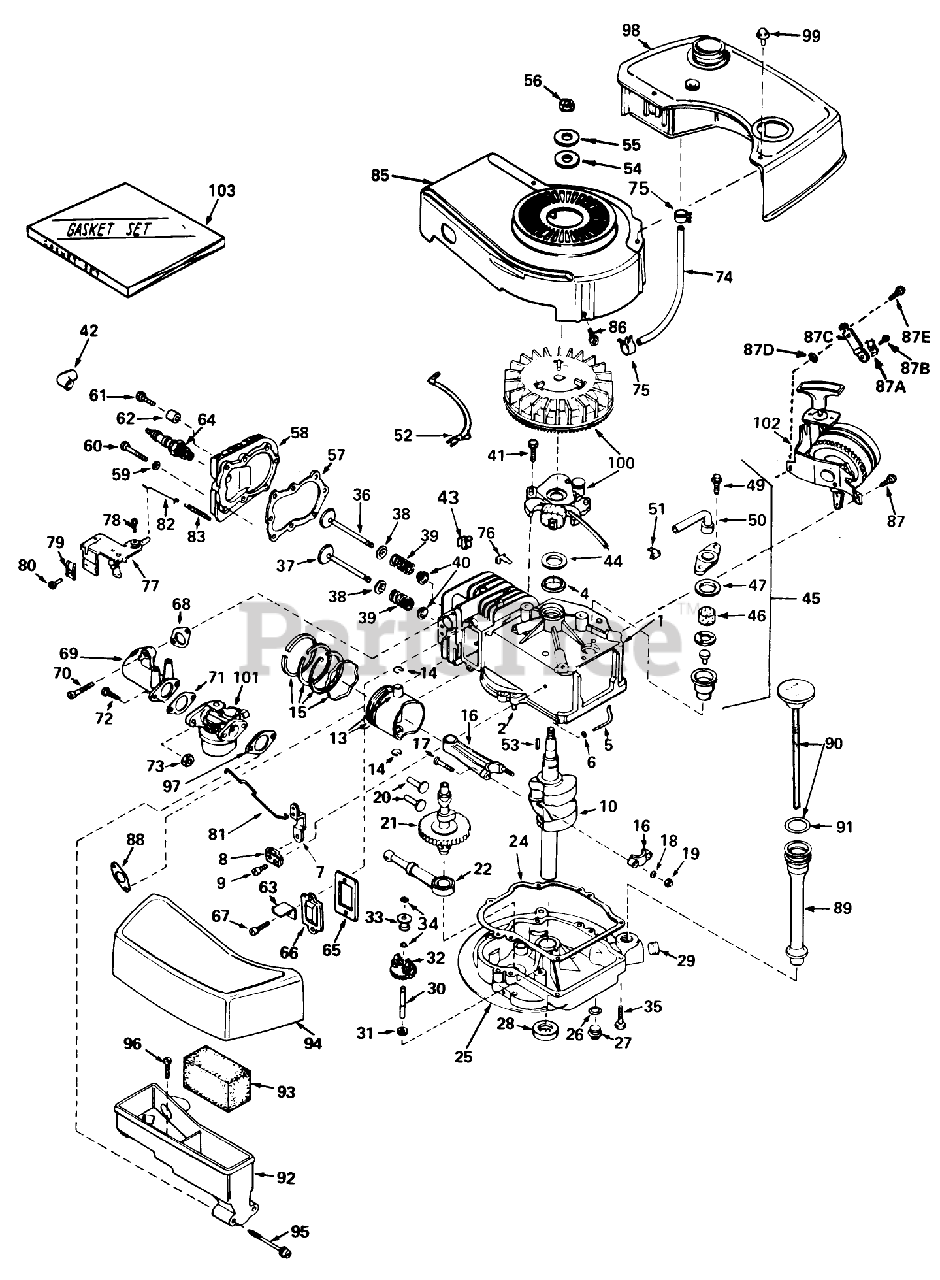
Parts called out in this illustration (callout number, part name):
1	Cylinder Assy. (Incl. Ref. #2, 4 105)
2	Pin-Dowel
4	OIL SEAL
5	Rod, Governor (Incl. No. 36)
6	Washer-Flat
7	Governor Lever
8	Clamp-Lever, Governor
9	Screw
10	Crankshaft
13	Piston Pin Assembly (Incl. 2 of No. 14) (.010 Oversize)
13	Piston Pin Assembly (Incl. 2 of No. 14) (.020 Oversize)
14	Ring-Retaining, Piston Pin
15	Ring Set Piston (Std.)
15	Ring Set Piston (.010 Oversize)
15	Ring Set Piston (.020 Oversize)
16	Rod Assy., Connecting (Incl. Ref. #17)
17	Bolt, Connecting
18	Washer
19	LOCKNUT
20	Lifter-Valve
21	Camshaft(Mech.Comp. Release)
22	Oil Pump ASM
24	Gasket, Mounting
25	Filter, Air Cleaner
26	Gasket-Oil Drain
27	Plug Oil Drain
28	Seal Oil
29	Plug Oil Drain
30	Shaft-Governor
31	Washer-Flat
32	Governor Gear ASM
33	Spool-Governor
34	Ring-Retaining
35	Screw (1/4-20 x 1-1/4)
36	Valve, Intake (Incl. Ref. #38, 39 40) (Std.)
36	Valve, Exhaust (1/32" Oversize) (Incl. Nos. 8, 9 10)
37	Valve, Exhaust (Standard) (Incl. Nos. 8, 9 10)
37	Valve, Exhaust (1/32" Oversize) (Incl. Nos. 8, 9 10)
38	Cap-Upper Valve Spring
39	Spring-Valve
40	Cap-Valve, Spring
41	Screw
42	Cover-Spark Plug
43	51004 GIL ROTARY TI
44	Gasket Stator
45	Breather Assy. (Incl. Ref. #46, 47, 49, 50 51 )
46	Element-Breather
47	Gasket-Breather
49	Screw, Hex Hd. w/Conical
50	Tube, Breaker
51	Clip, Breather
52	Wire Ground
53	Key-Flywheel
54	Washer Flat
55	Washer-Spring
56	Hex Nut
57	63573 GIL 42 SNWTHW
58	Head Cylinder
59	Washer
60	Screw
61	Screw Hex Hd. Cap
62	Space
63	Retainer Clip
64	Plug, Spark (J17LM or equiv.)
65	Gasket-Breather
66	Cover-Valve
67	Screw
68	Gasket, Intake
69	Pipe, Intake
70	Screw (1/4-20 x 1)
71	Gasket-Carburetor
73	Nut and Lock Washer (1/4-28)
74	Line-Fuel
75	Clamp-Line, Fuel
76	Clip-Wire
77	Control Assy., Speed (Incl. Nos, 76, 78 89)
78	Screw (10-24 x 3/4)
79	Conduit
80	Screw (10-32 x 3/8)
81	Link Governor
82	Link Governor Spring
83	Spring Governor
85	Housing, Blower
86	Screw
87	Screw (1/4-20 x 1/2)
87A	Conduit
87B	Screw (10-32 x 3/8)
87C	Bracker
87D	Washer
87E	Screw (1/4-20 X 5/8)
88	Gasket Exhaust
89	Tube Fill
90	Dipstick, Oil (Incl. Ref. #101)(Twist Lock)
91	O-Ring
92	Body Air Cleaner
93	Filer, Air
94	Cove, Air Cleaner
95	Screw Fil Hd.
96	Screw, Hex Hd.
97	Gasket-Air Cleaner
98	Tank Fuel
99	Screw (10-32 x 35/64)
100	Magneto
101	Carburetor (Incl. No. 71)
102	Starter
103	53024/VAR.16HP O/P
